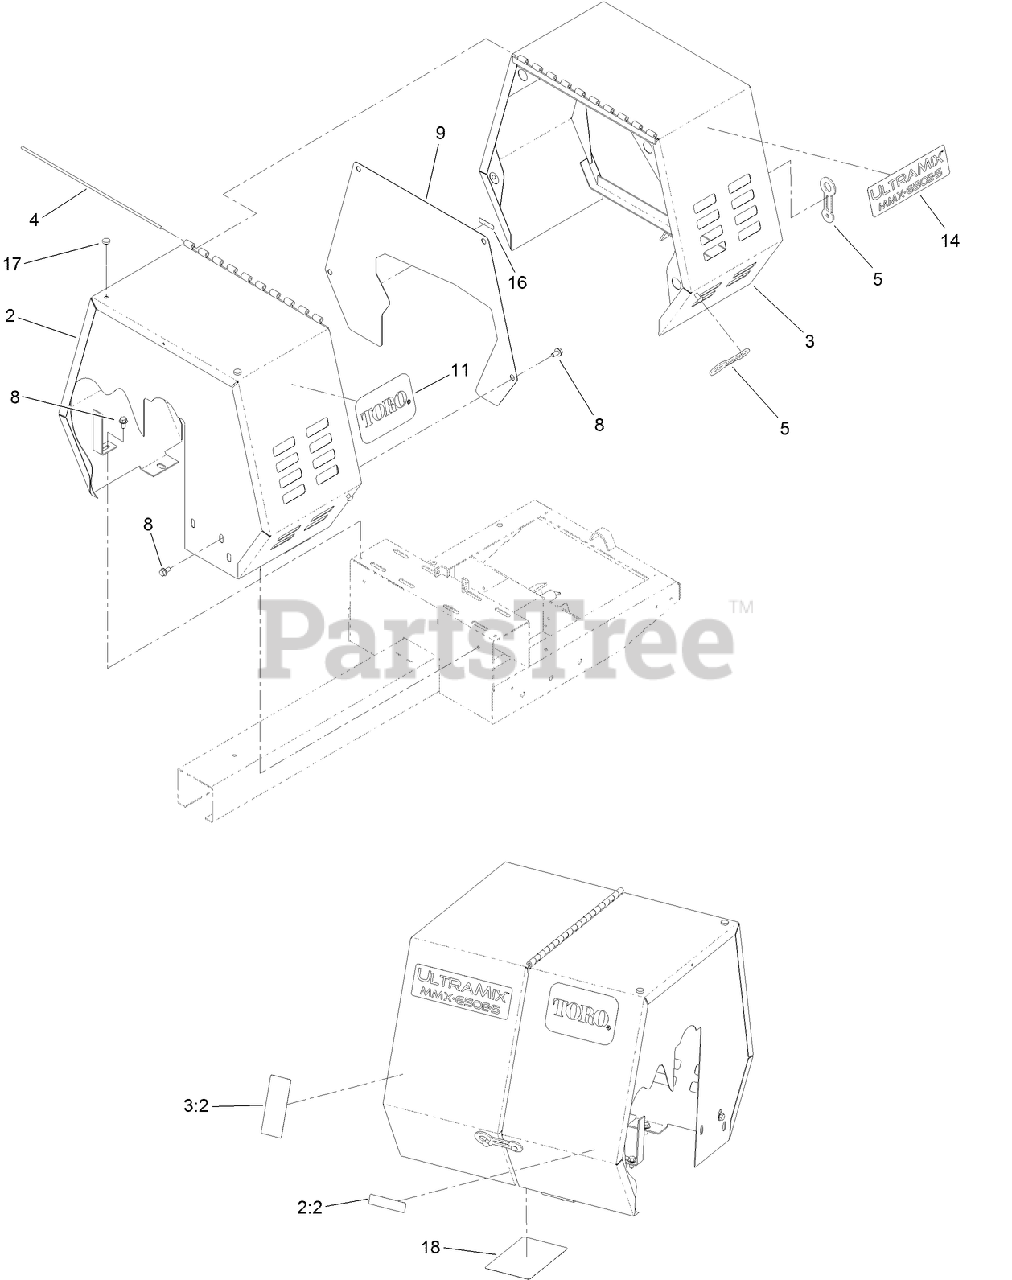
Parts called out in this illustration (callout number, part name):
2	STATIONARY COWL ASM
2:2	DECAL-ARRESTER, SPARK
3	MOVABLE COWL ASM
3:2	DECAL-WARNING
5	LATCH-RUBBER
8	SCREW-HWH
9	PLATE-ACCESS, BELT
11	DECAL
16	DECAL-GREASE
17	BUMPER
18	DECAL-SERVICE
